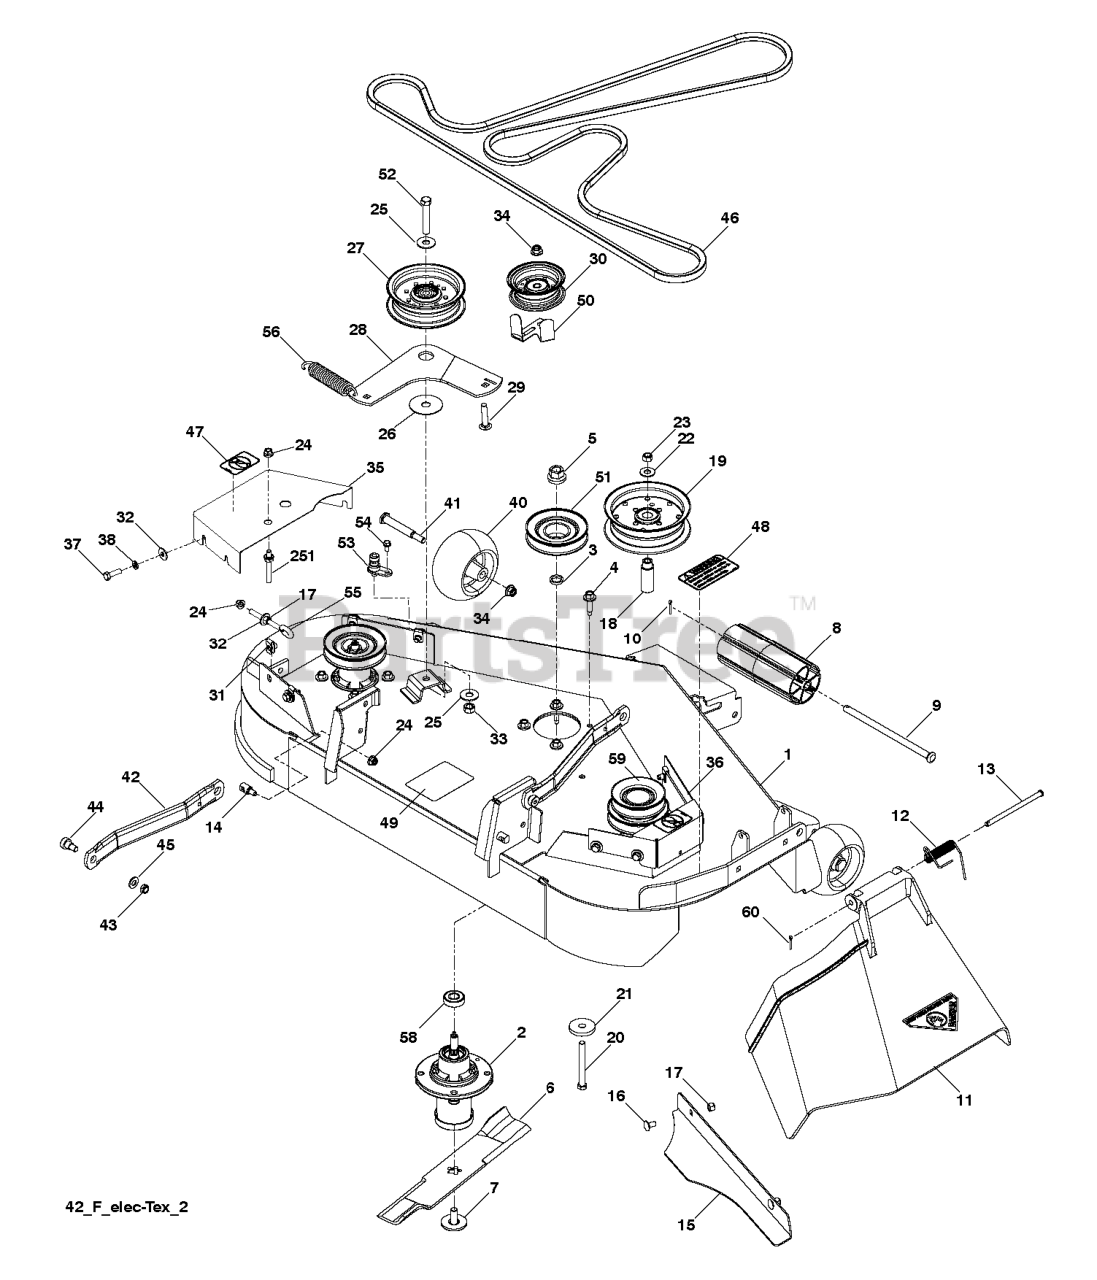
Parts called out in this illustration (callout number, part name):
1	DECK SVC W/DECALS 42 YTH ORNGE
2	MANDREL.DECK.ASSEMBLY
3	WASHER.SPACER.MANDREL
4	WASHER HEAD SCREW
5	NUT.FLANGE.LOCK.TOP
6	BLADE, 14 5/8"
7	BOLT.WASHER.ASM.7/16-2
8	NOSE ROLLER 48"
9	ROD.ROLLER.NOSE.NARROW.48"
10	PIN.COTTER.5/16.BOW TI
11	DISCHARGE CHUTE 42"
12	SPRING - TORSION
13	PIN, CLEVIS 5/16 X 5.19
14	STUD.FASTNER.W/ANTI-ROTATE
15	PLATE.CONFINEMENT.42"
16	CARRIAGE BOLT 5/16C X 5/8"
17	NUT 5/16 NYLOC
18	BUSHING, IDLER
19	PULLEY, IDLER
20	HCS 3/8-16 X 3-1/2 GR5 ZD
21	SPINDLE WASHER
22	WASHER 3/8 FLAT
23	NUT 3/8-16 NYLOC
24	5/16-18 NYLOC FLANGE NUT
25	WASHER 7/16 FLAT ZD
27	PULLEY.IDLER.MWR.STATI.LH
28	ARM, IDLER, BLK
29	RHSNB 3/8-16X1-3/4
30	PULLEY.IDLER.FLAT
31	U-CLIP 5/16-18 NUT RETAINER
32	WASHER 5/16 FLAT
33	NUT 7/16-14 HEX WHIZ LK
34	NUT 3/8-16 HEX FLG NYLOC ZD
37	HCS 5/16C X 1
38	WASHER.LOCK.HVY.HLCL.SPR.5/16
40	GAUGE WHEEL
41	BOLT.SHOULDER.3/8-16X3-5/8.
42	ARM.SUSPENSION.MOWER
43	NUT HEX 3/8-16 NYLON, THIN
44	SB 3/8-16 X 3/8 SKT HD ZD
45	WASHER 3/8 SAE FLAT
46	BELT, 42" FAB DECK
47	DECAL, NO STEP
48	DECAL, CAUTION
49	DECAL.MOWER.SCH.48/54
50	BELT GAURD
51	PULLEY, MANDREL 4.08 OP
52	BOLT 7/16-14 X 2-1/2 GR 5 ZD
53	PORT.WASHOUT
54	BOLT 1/4-20 X 1/2 HWST
55	EYE BOLT 5/16 X 3.50
58	BEARING, BALL
59	PULLEY, COLLECTION 42
60	RETAINER CLIP
251	KEEPER,DRIVE BELT
